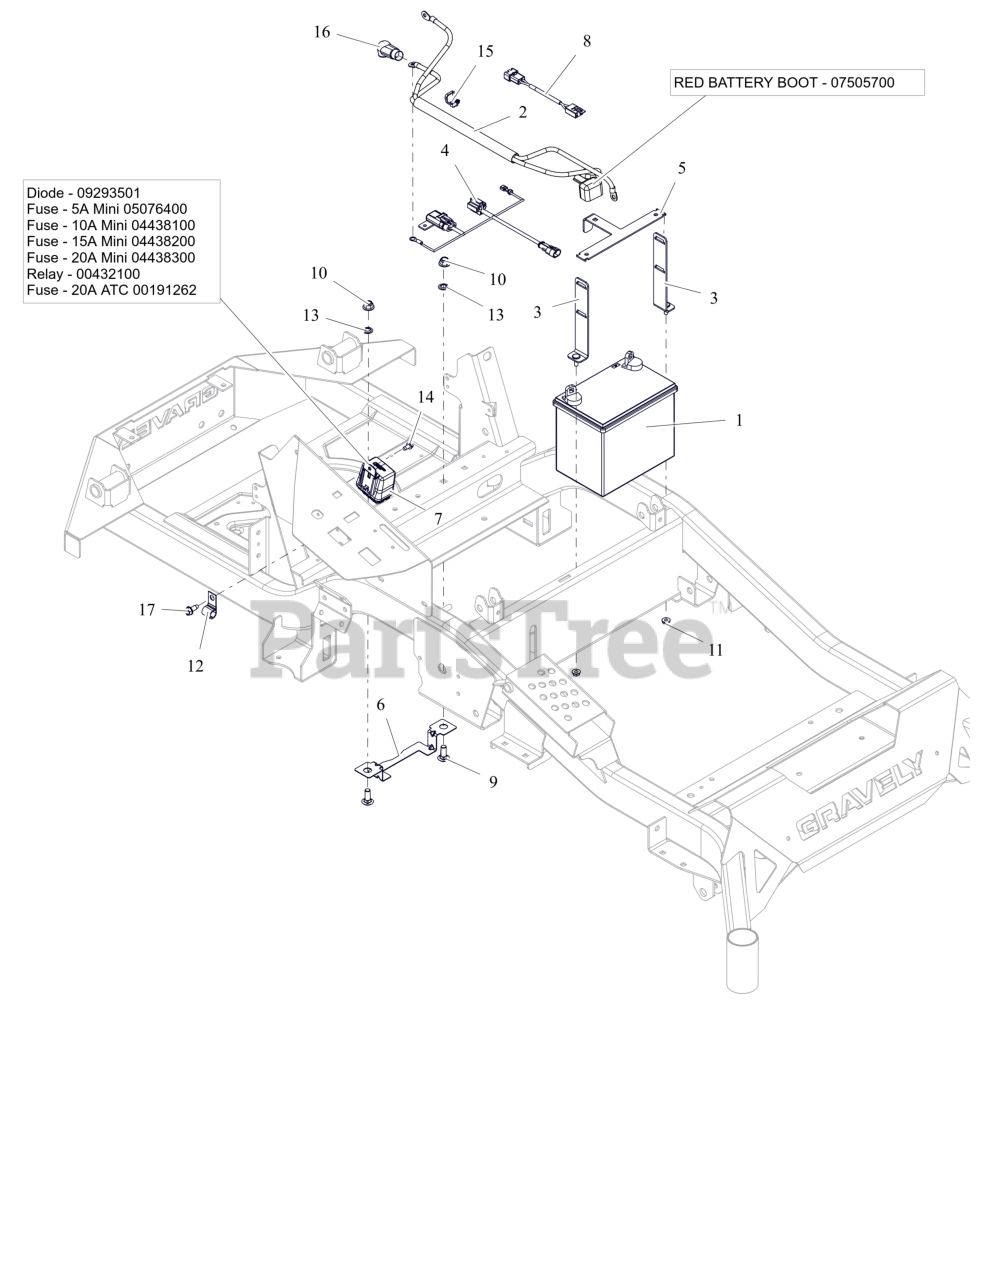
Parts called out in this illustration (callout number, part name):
1	BATTERY, 300 CCA 10U1L
2	HARNESS, BATTERY HD
2	INSULATOR
3	WMT,BATTERY MOUNT HOLD DOWN
4	HARNESS, STARTER ADAPTER
5	BRKT, BATTERY TIE DOWN
6	GUARD, ELECTRICAL HARNESS
7	HARNESS, WIRE
7	RELAY,MICRO5 TERML W/RESISTOR
7	DIODE, CONNECTOR SHELL
7	FUSE, 5 AMP MINI-ATC
7	FUSE,10 AMP MINI-ATC
7	FUSE,15 AMP MINI-ATC
7	FUSE,20 AMP MINI ATC
7	FUSE, 20 AMP BLADE S/O
8	HARNESS- EXTENSION
9	BLT, RHSN .38-16X1.00 G5 ZCC
10	NUT,NYL-FLG .38-16 GF ZCC
11	NUT-LK-TOP-FLG .250-20 GF ZCC
13	NUT-PUSH .38 DIA. PAL ZINC
14	SCR-TAP .25-20X.50 HWH ZCC
15	CABLE TIE W/ TREE (.25 HOLE)
16	BOOT, .65ID POS
17	SCR,TAP .312-18X.75 HWH TR ZCC
